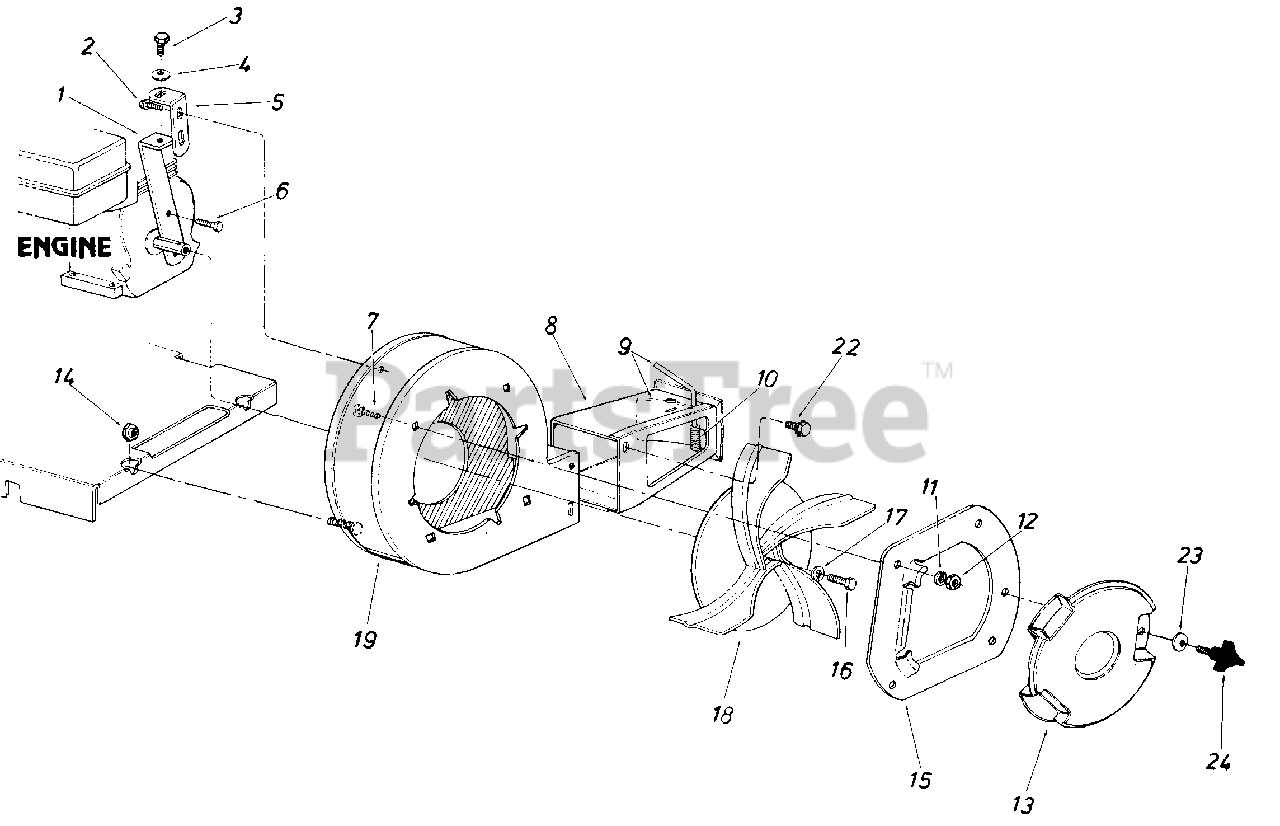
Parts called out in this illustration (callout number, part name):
3	Hex Bolt 5/16-18 x .75" Lg.*
4	L.-Wash. 5/16" I.D.*
7	Carriage Bolt 5/16-18 x .62" Lg.*
11	L.-Wash. 5/16" I.D.*
12	Hex Nut 5/16-18 Thd.*
13	Blower Guard
14	Hex Shoulder Nut .50" I.D.
15	Nozzle Plate Ass'y.
16	Hex Bolt 3/8-24 x 1.25" Lg.*
17	L.-Wash. 3/8" I.D. HD.
18	Air Vane Plate Ass'y.
19	Blower Housing Ass'y.-Comp.
22	Hex Sems Bolt 5/16-18 x .62" Lg.*
23	Belleville Wash. 34" 1 .D. x .87" O.D.
24	3-Arm Thumb Scr. 5/16-18 x .75" Lg.
